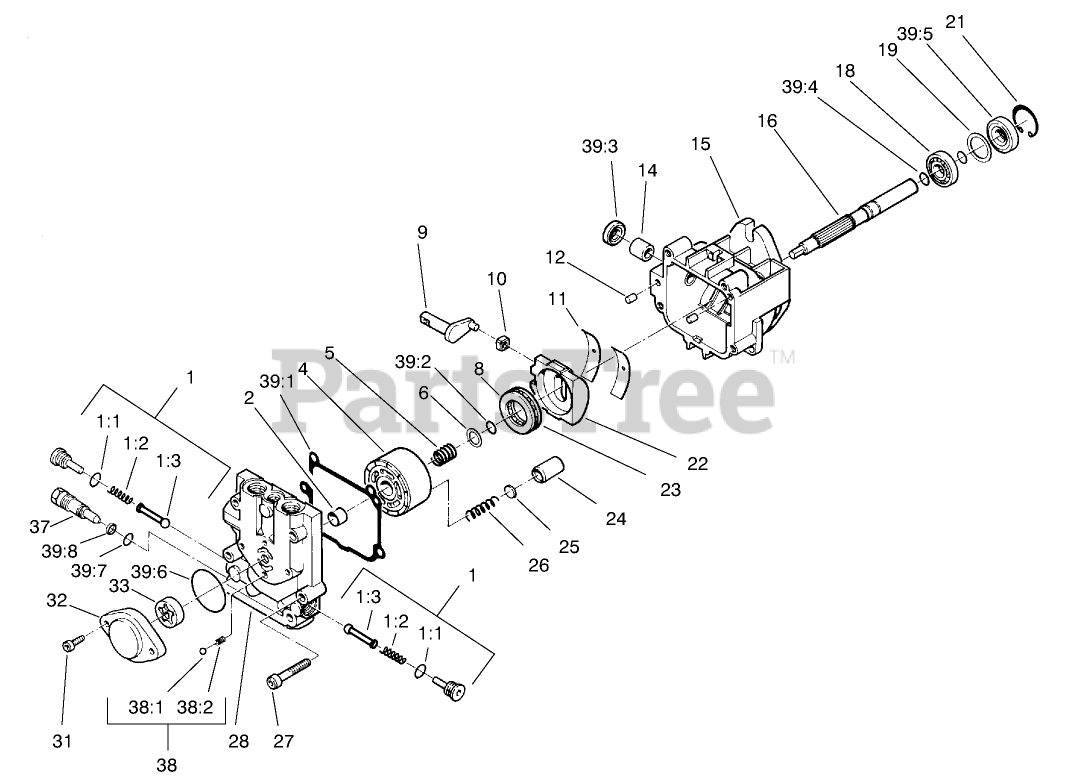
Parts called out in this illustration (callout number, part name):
1	CHECK VALVE KIT
1:1	Seal-Dust
1:2	Spring
1:3	Poppet
2	Journal-Bearing
4	Cylinder Block
5	Spring
6	Washer
8	Plate-Thrust
9	Arm-Trunion
10	Guide-Slot
11	Cradle-Bearing
14	Journal-Bearing
15	Housing
16	Shaft
18	Bearing-Ball
21	Ring-Retaining
22	Swashplate ASM
23	Roller-Thrust
25	Washer-Thrust
26	Spring-Piston
28	End Cap
32	Housing-Charge Pump
33	Gerotor ASM
37	Valve-Bypass
38	RELIEF VALVE CHARGE KIT
38:1	Ball
38:2	Spring
39:1	Gasket-End Cap
39:2	Ring-Retaining
39:3	Seal-Lip
39:4	Ring-Retaining
39:5	Seal-Lip
39:6	Seal-Dust
39:7	Seal-Dust
39:8	Ring-Back Up
